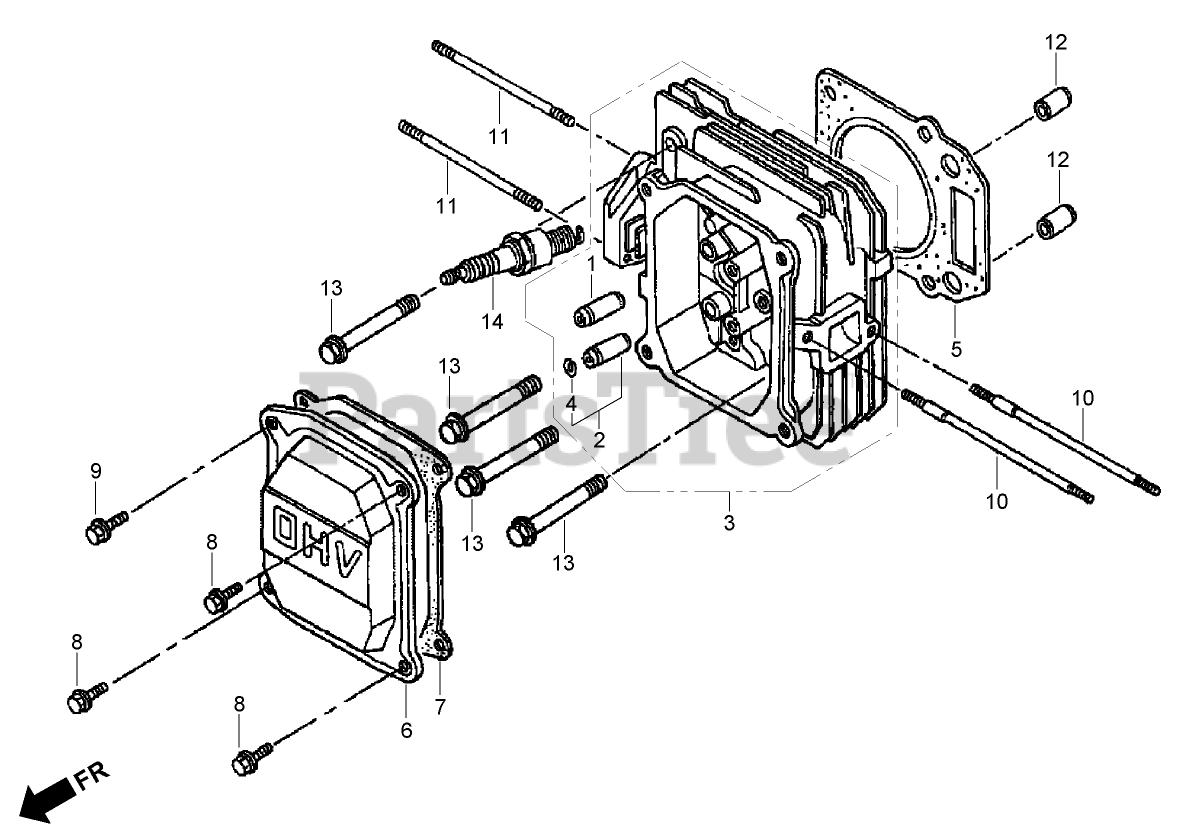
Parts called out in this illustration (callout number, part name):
1	GUIDE-VALVE (O S)
2	GUIDE-VALVE, EXHAUST (O S)
3	HEAD-CYLINDER
4	CLIP-GUIDE, VALVE
5	GASKET-HEAD, CYLINDER
6	Cover-Head
7	GASKET-COVER, CYLINDER HEAD
8	BOLT-FLANGE (6X12) (C T200)
8	BOLT-FLANGE (6X14) (C T200)
9	BOLT-FLANGE (6X14) (C T200)
10	BOLT-STUD (6X109)
11	BOLT-STUD (6X85)
12	PIN-DOWEL (10X16)
13	BOLT-FLANGE (8X50)
14	SPARK PLUG (B P R4E S) (N G K)
14	SPARK PLUG (W14E P R-U) (DENSO)
14	SPARK PLUG (B P R 5E S) (N G K)
14	SPARK PLUG (W16E P R-U) (DENSO)
14	SPARK PLUG (B P R 6E S) (N G K)
14	SPARK PLUG (W20E P R-U) (DENSO)
